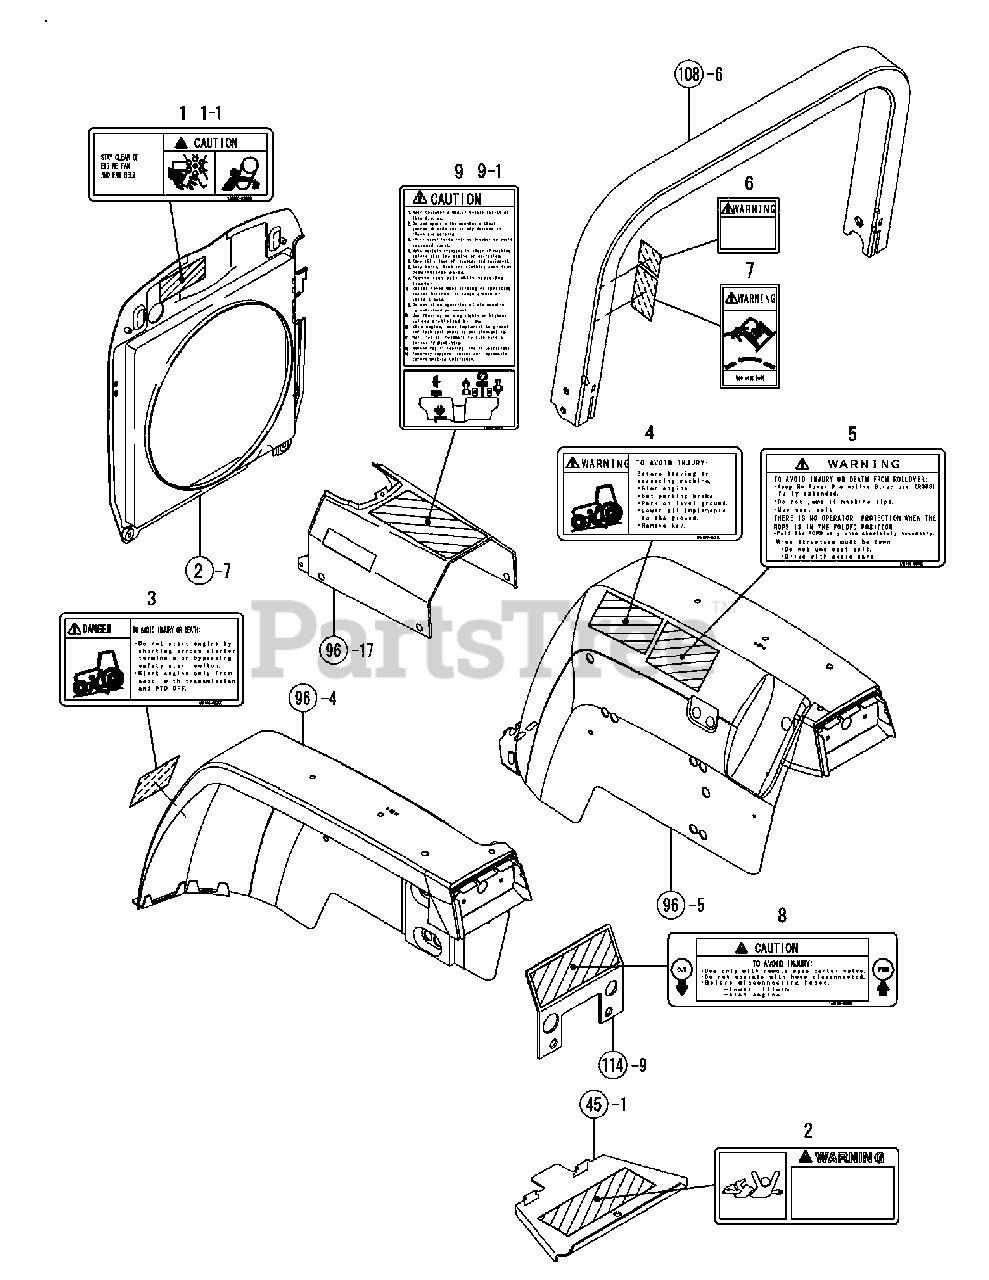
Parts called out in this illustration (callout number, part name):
1	LABEL, CAUTION, FAN
1-1	LABEL,WARNING, FAN
2	LABEL, P.T.O. WARNING
3	LABEL, DANGER, START
4	LABEL, WARNIBG, STOP
5	LABEL, WARNING, ROPS
6	SAFETY DECAL
7	SAFETY DECAL (BELT)
8	LABEL, CAUTION, REAR
9	LABEL, CAUTION
